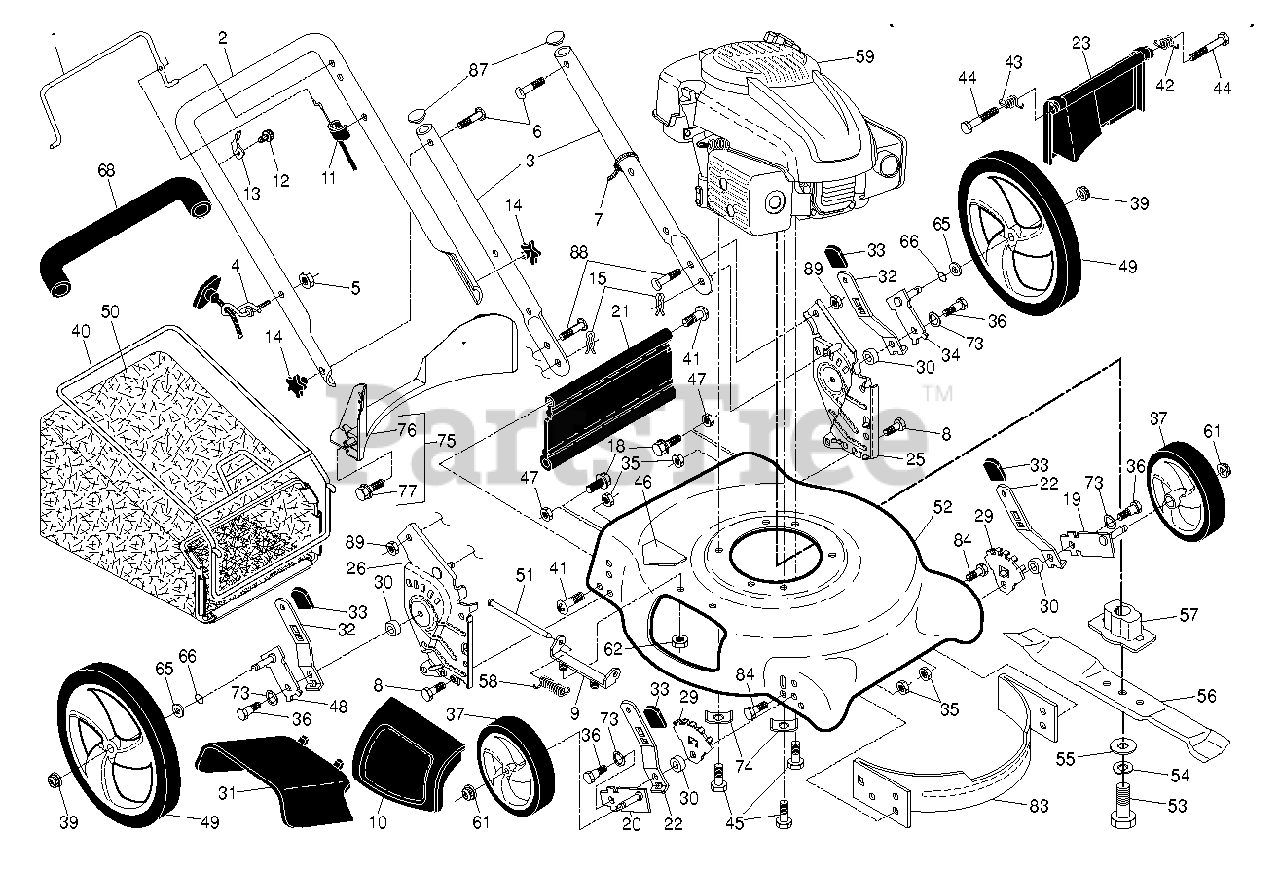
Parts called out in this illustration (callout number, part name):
1	BAIL.CONT.D.STRAIGHT.PUSH.BLK
10	MULCH DOOR
11	CABLE.MZR.RATO.22"LOW.
32	SPRING.SEL.22.ECON.HI-WHL.RATO
56	21" BLADE
57	ADAPTER.BLADE.W/KEY.25MM.CE
61	NUT.HEX.FLANGE.3/8-16.LOCKNUT
62	LOCKNUT
77	SCREW.HX.13X.750
83	BAFFLE.FRONT.21.DOME.US
87	PLUG.PLASTIC.7/8".14-20.GAUGE
